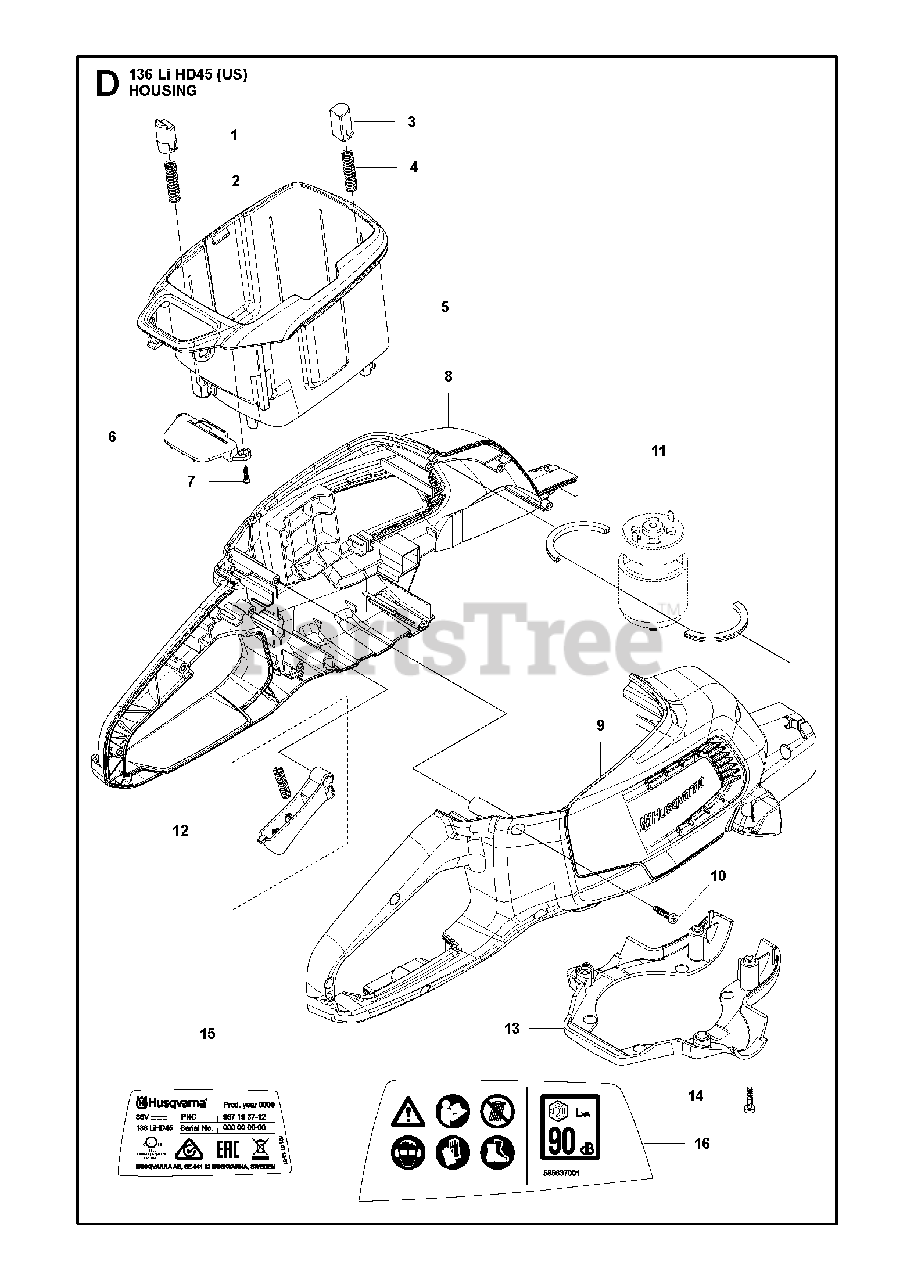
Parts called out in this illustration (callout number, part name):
1	PUSH BUTTON
2	SPRING PUSH BUTTON
3	PUSH BUTTON FRONT
4	SPRING PUSH BUTTON
5	BATTERY BOX
6	BRACKET KEYPAD
7	SCREW ST3X8
8	HOUSING RIGHT
10	SCREW ST4X16
13	COVER BOTTOM
14	SCREW ST4X16
